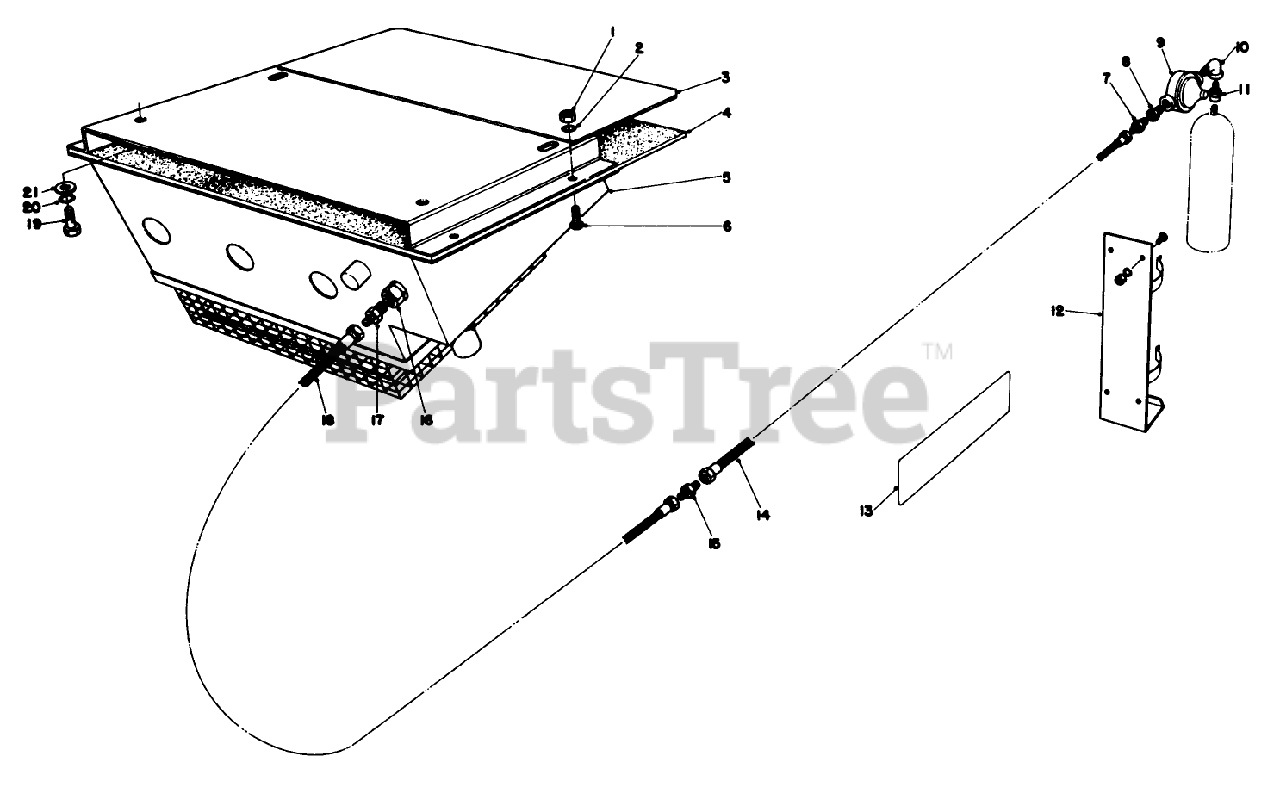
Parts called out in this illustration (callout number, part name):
1	NUT-HEX
2	WASHER-LOCK
3	Mounting Bracket
4	Heat Shield
5	Heater-Catalytic
6	SCREW-PPH
7	1/4 MPT x 9/16 L.H. Adapter
8	3/8 MPT x 1/4 FPT Bushing
9	W.G. Regulator
10	1/4 FPT x 1/4 MPT Street Elbow
11	Tool Din
12	Cylinder Bracket
13	Decal-Danger
14	72" Lg. Fuel Line
15	Hose Connector 9/16 L.H. x 9/16 L.H. Union
16	1/4 FPT x 1/8 FPT Adaptor
17	9/16 x 1/4 MPT Adaptor
18	48" Lg. Fuel Line
19	SCREW-HH
20	WASHER-LOCK
21	WASHER-FLAT
